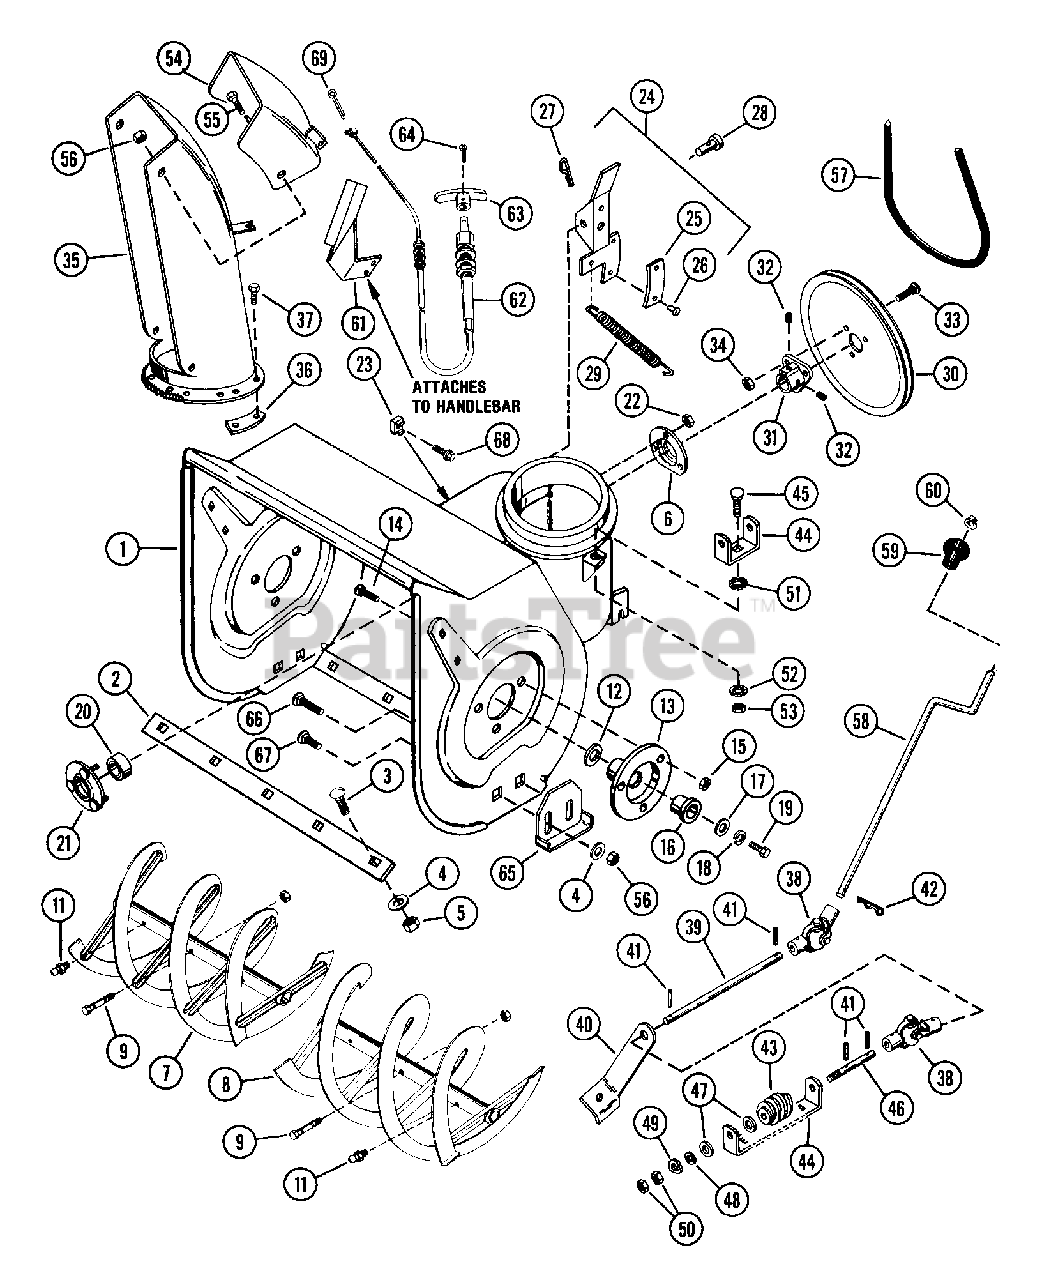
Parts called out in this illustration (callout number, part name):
1	HOUSING, BLOWER - 36 INCH
2	SCRAPER BLADE 36"
3	BLT-RDHDSQNK .312-18X.62 PL
4	WSHR-FL-STL .38X.875X.083 PL
5	NUT-LK .312-18 GR A PL
6	BEARING FLANGE
7	RAKE, RIGHT-36"(1ID X 15.75OD)
8	RAKE, LEFT-36"(1"ID X 15.75OD)
9	SHEAR BOLT SERVICE ASSEMBLY
11	SPIN DRIVE ZERK FITTING
12	WSHR-FL-STL 1.010X1.505X.062PL
13	BEARING SUPPORT
14	BLT-SERNK SL .25-20X.50 PL
15	NUT-LK-FLG .250-20 PL
16	BSHG-FLG 1.000X1.12X.62X1.50BR
17	WSHR-FL-STL .511X1.441X.125 PL
18	WSHR-LK .500X.151 HVY PL
19	BLT-HEX .50-13X1.00 PL GR2
20	BRG-BALL 1.0X2.0X.56
21	BEARING FLANGE
22	NUT-LK-CTR .250-20 PL
23	NUT-RETNR .38-16 TINRMAN
24	BRAKE ARM ASSEMBLY
25	BRAKE LINING
26	RVT-TBLR .187X.437 RH ST PL
27	PIN-HAIR INT .06X.18X.77
28	PIN-CLEV .371X1.16 YWZC
29	SG-TENS .062X.56X8.0 WLD 11
30	PLY-V 9.0 X 1.25 3BLT
32	SCR-SET .32-18X.38 SKHCUPNL OH
33	BLT-SERRDHD SL .31-18X.87 PL
34	NUT-FLG. .312-18 PL
35	DISCHARGE CHUTE - 36 IN
36	CHUTE CLAMP
37	SCR-TAP 10-24X.375 HWH PL TR
38	UNIVERSAL JOINT ASSY
40	CHUTE CRANK BRACKET
41	PIN-ROLL .125X.75
42	PIN-HAIR INT .08X.38X1.42 YWZC
43	WORM GEAR L.H.
44	WORM CLEVIS
45	BLT-RDHDSQNK .31-18X.75 GR5 PL
46	WORM SHAFT
47	WSHR-PLASTIC .390X.875X.062
48	WSHR-FL-STL .390X.875X.18 PL
49	WAVE WASHER .390X.655X.110
50	NUT-JAM .375-16 PL
51	WSHR-LK-EXT .375X.035 PL
52	WSHR-LK .313X.062
53	NUT-JAM .50-20 LH THD PL
54	CHUTE DEFLECTOR
55	BLT-HEX .38-16X.75 PL GR2
56	NUT-LK-CTR .375-16 GR A PL
57	V-BELT, 4L-RAW EDGE
58	CHUTE CONTROL CRANK
60	CAP, 3/8 ROD YWZC
61	BRACKET - DEFLECTOR CONTROL
62	CONTROL CABLE
63	TEE HANDLE
64	SCR-MCH 10-32X.50 SLPAN SS
65	RUNNER - SKID SHOE
66	BLT-RDHDSQSHNK .38-16X1.00 PL
67	BLT-RDHDSQNK .38-16X.75 SHT PL
68	BLT-SCRHFWH .38-16X.75 PL
69	PIN-COTR .12X.75 PL
